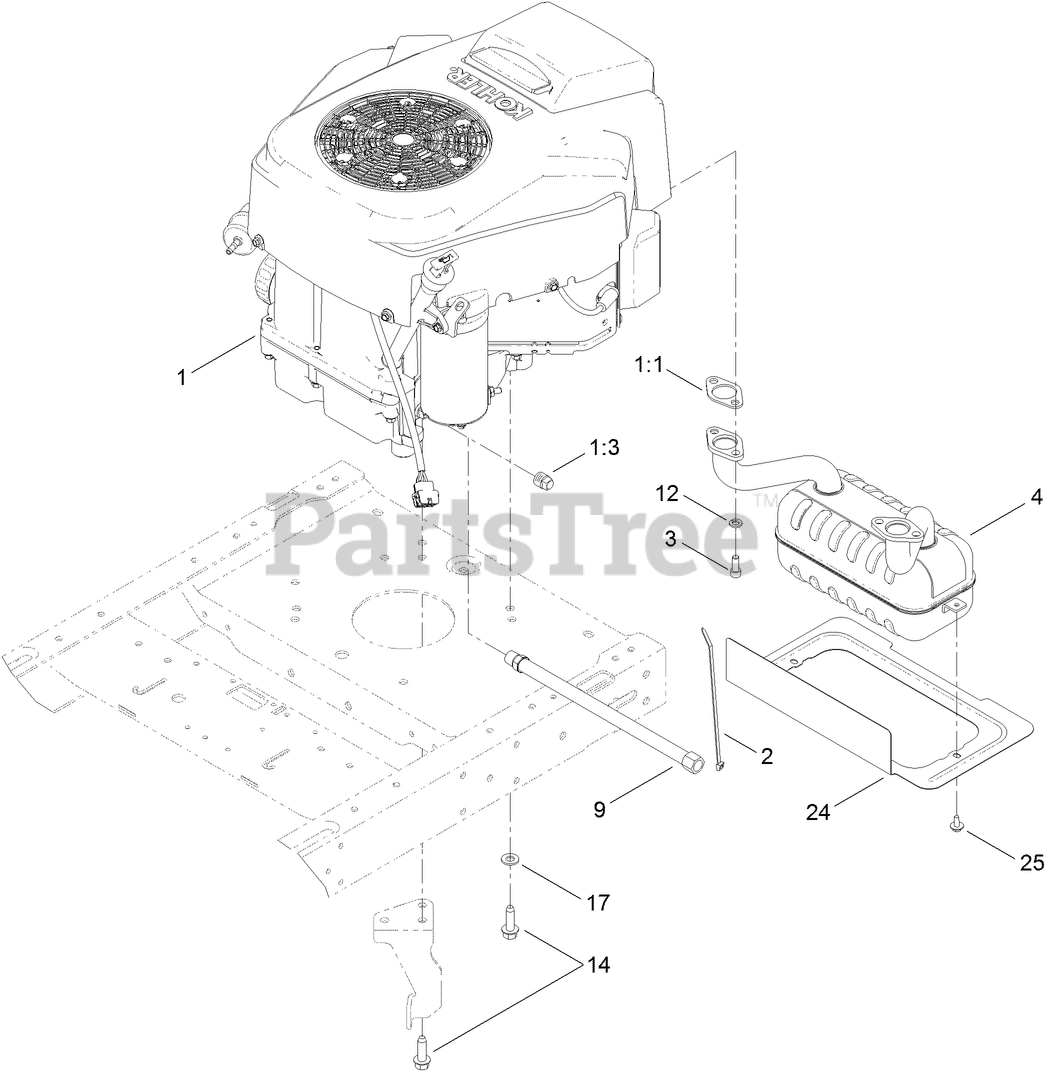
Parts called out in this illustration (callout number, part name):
1:1	GASKET-EXHAUST
1:3	PLUG-PIPE, SQH
2	TIE-CABLE
3	SCREW-HSH
4	MUFFLER-KOHLER
9	HOSE-DRAIN, OIL
12	WASHER-LOCK
14	SCREW-THD
17	WASHER-FLAT
24	SHIELD-HEAT
25	SCREW-HHFTF
